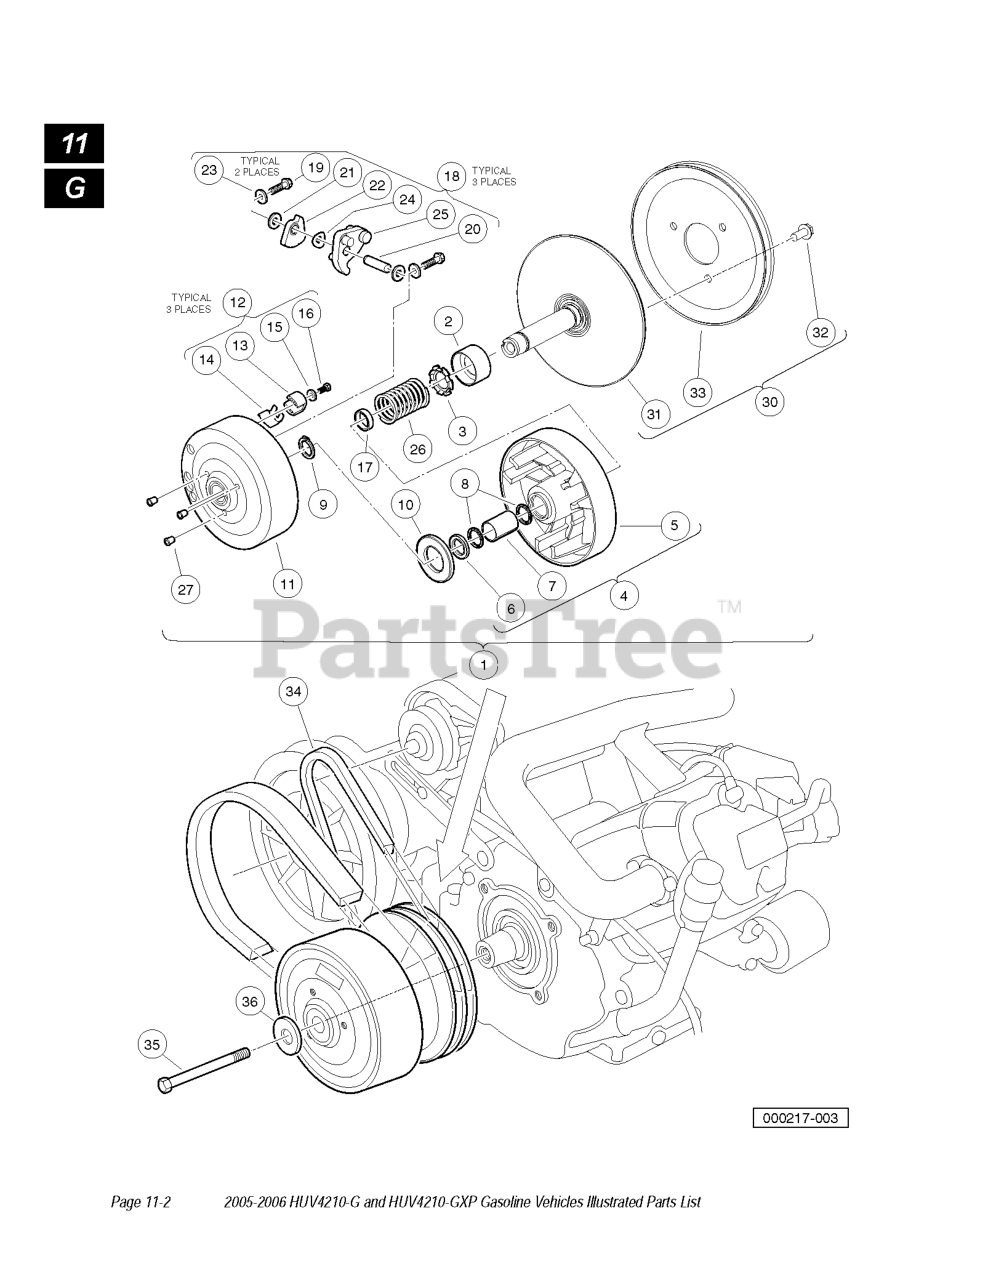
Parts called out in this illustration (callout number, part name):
1	DRIVE CLUTCH ASSY. FE 350/272
2	BEARING IDLER
3	RETAINER, SPRING
4	MOVABLE FACE ASSEMBLY
8	RING, SPIRAL BACKUP
9	RING .810" INTERNAL
10	WASHER, THRUST
11	DRIVE HUB ASSY
12	DRIVE CLUTCH BUTTON KIT
13	DRIVER, DRIVE CLUTCH
14	SPRING, DRIVE BUTTON
15	WASHER FLAT
16	SCREW, # 10-24 X .50 HEX
17	SPACER, FIXED FACE SHAFT
18	DRIVE CLUTCH WEIGHT KIT DS OHV
19	SCREW, 1/4-20 X 1.00 HEX HEAD
24	WASHER, WAVE
26	SPRING-DRIVE CLUTCH FE350
28	KIT, FXD FACE DR ASM FE290/350
34	BELT, STARTER-GENERATOR
35	SCREW 3/8-24X5.5 HEX LOC PTCH
36	WASHER, 3/8 TYPE B FLAT
